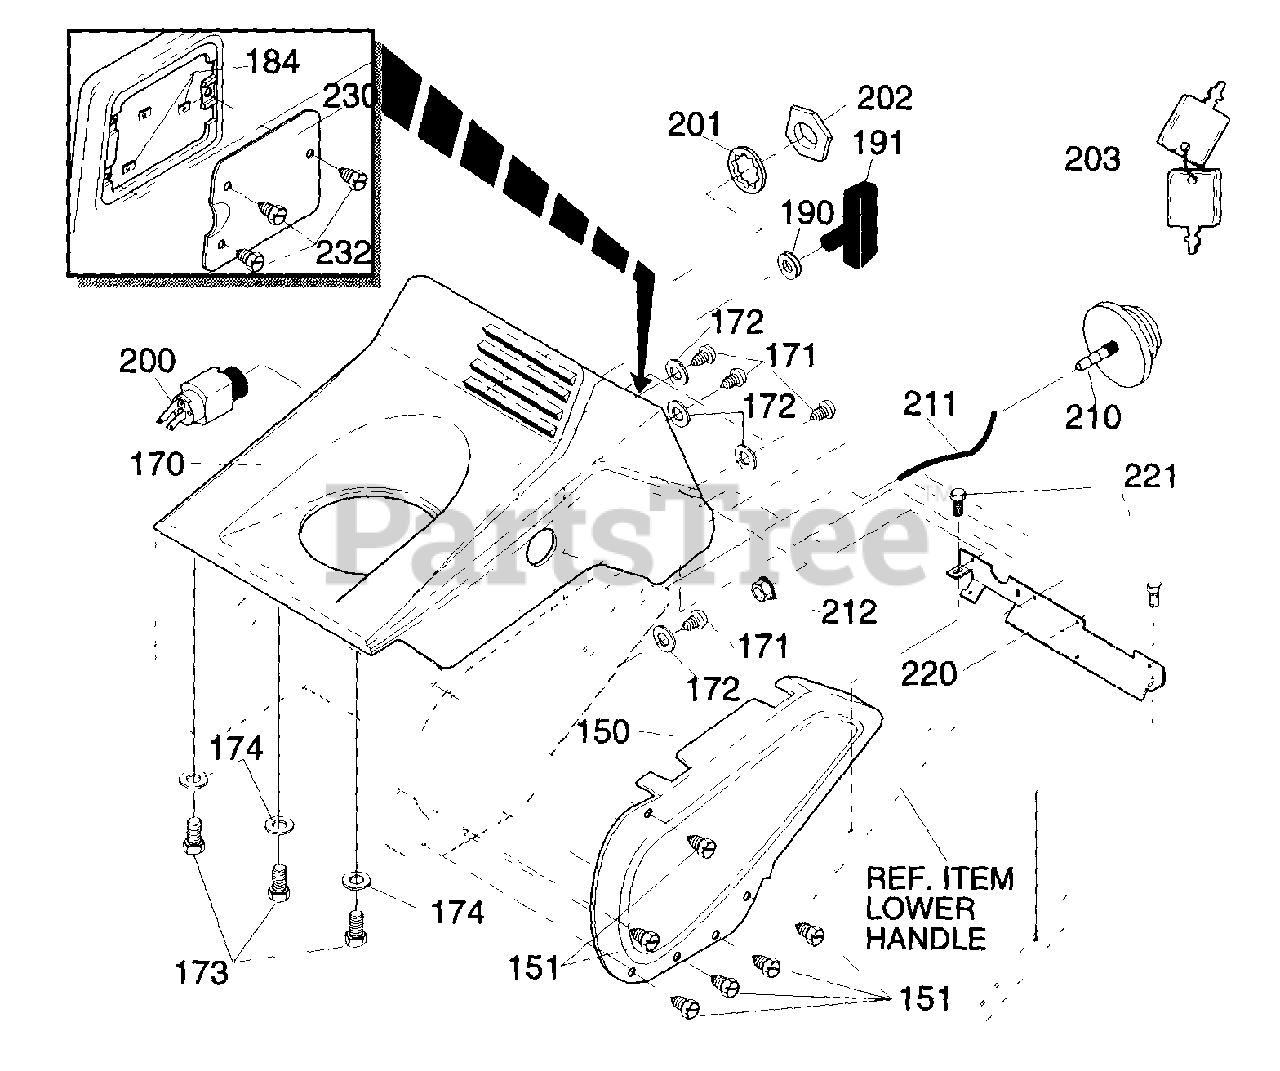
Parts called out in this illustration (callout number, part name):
150	BELT COVER
151	SCREW, 10-24X 38
170	COVER, TOP
171	SCREW, #10-24X 50
172	FLATWASHER 203X 56X 049
173	SCREW, #10-24X 63
174	FLATWASHER 250X 56X 049
184	NUT, TINN "U" TYPE
190	GROMMET & WASHER
191	GRIP, MITTEN
200	SWITCH, IGNITION
201	WASHER, REGINTLK
202	NUT, 5/8-32 HXHD IGN SWITCH
203	2 KEYS & RING ASSY
210	PRIMER, ENGINE
211	HOSE, PRIM
212	NUT, 114-20 HEXKEPS
220	BRACKET, SHROUD MTG
221	SCREW #10-24X 63 TAP
232	SCREW #10-16X 75
